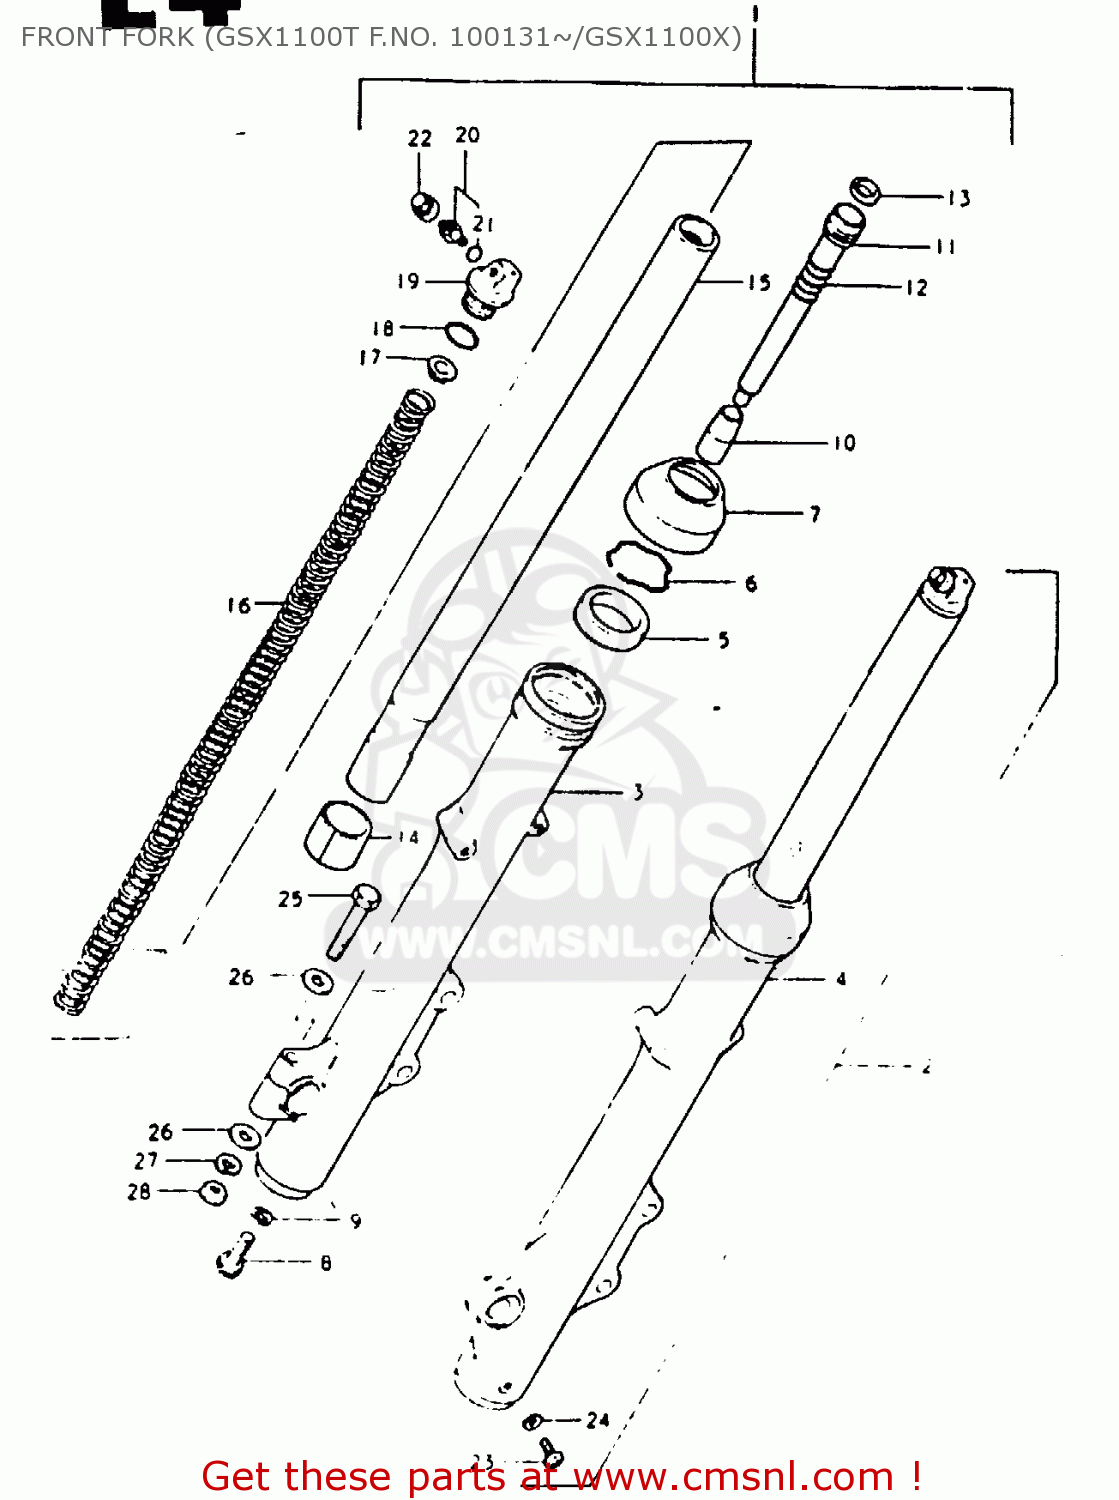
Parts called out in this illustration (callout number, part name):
1	DAMPER ASSY, RH
2	DAMPER ASSY, LH
3	TUBE,FORK,OUTER,RIGHT
4	TUBE,OUTER,LEFT
5	OIL SEAL,FRONT FORK
6	RING,STOPPER
7	SEAL,DUST
8	BOLT,FORK CYLINDER(10X25)
9	GASKET (NAS)
10	PIECE,OIL LOCK
11	CYLINDER
12	SPRING,FORK REBOUND
13	RING,PISTON
14	PISTON
15	INNER TUBE
16	SPRING
17	GUIDE,FRONT FORK SPRING C
18	O RING
19	CAP
20	VALVE
21	O RING
22	CAP,VALVE
23	SCREW
24	GASKET,DRAIN,PLUG (NAS)
25	BOLT 8X50
26	WASHER
27	WASHER,LOCK,8.
28	NUT
